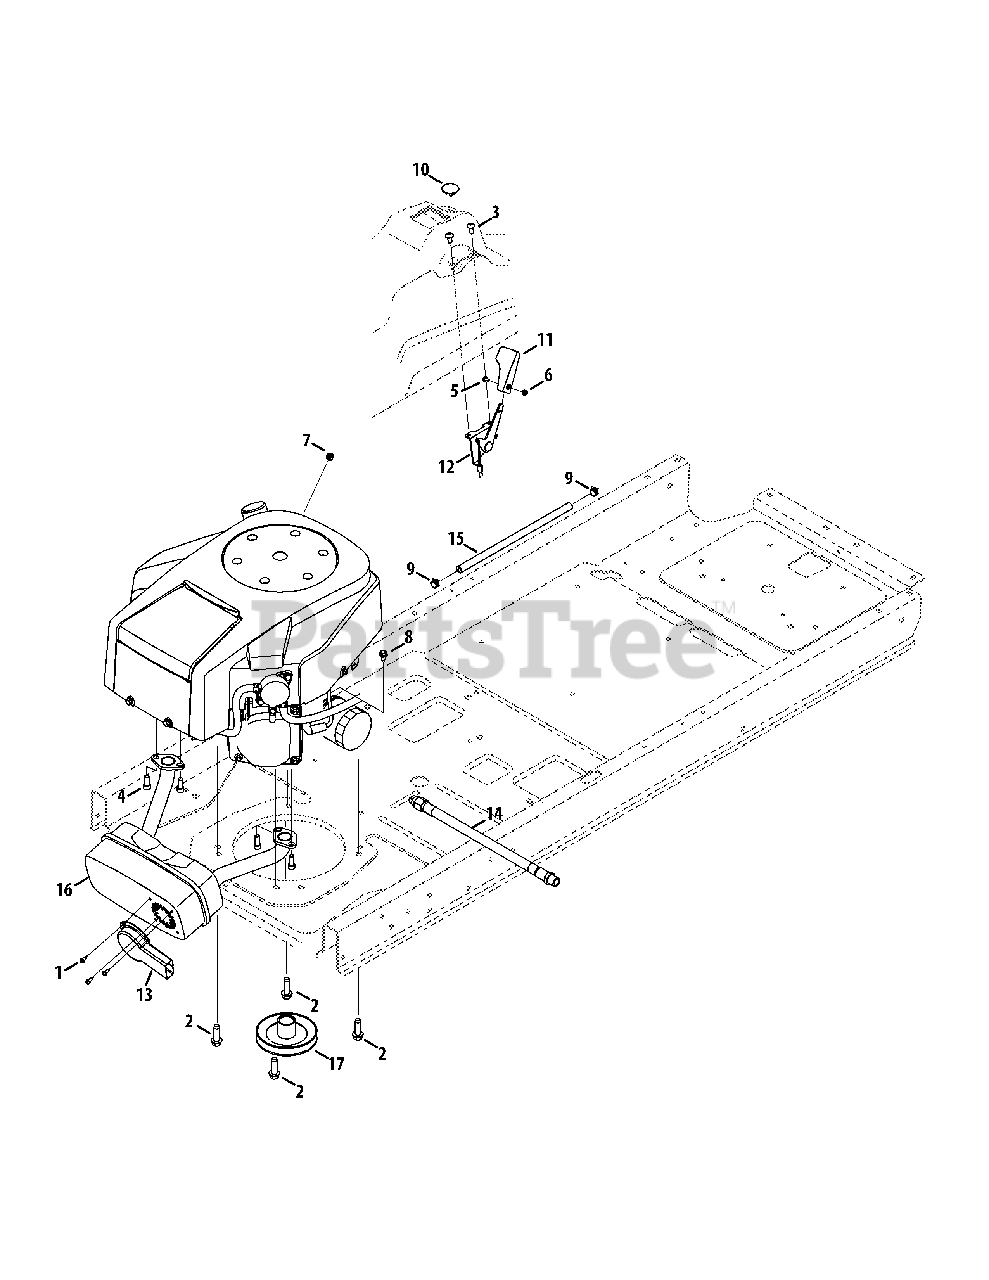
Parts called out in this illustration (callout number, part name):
1	Hex Washer Screw #8-18 x .500
2	Hex Washer Screw 3/8-16 x 1.00
3	Screw 1/4-20 x .50
4	Socket Head Screw 5/16-18 x .750
5	Screw #8-32 x .375
6	Hex Nut #8-32
7	Flange Lock Nut, 1/4-20
8	Hex Washer Screw 1/4-20 x .625
9	Hose Clamp .490 Dia.
10	Choke Plug
11	Throttle Control Knob
12	Throttle/Choke Control Cable
13	Muffler Deflector
14	Oil Drain Hose
15	Fuel Hose, 1/4
16	Twin Muffler
17	Engine Pulley
